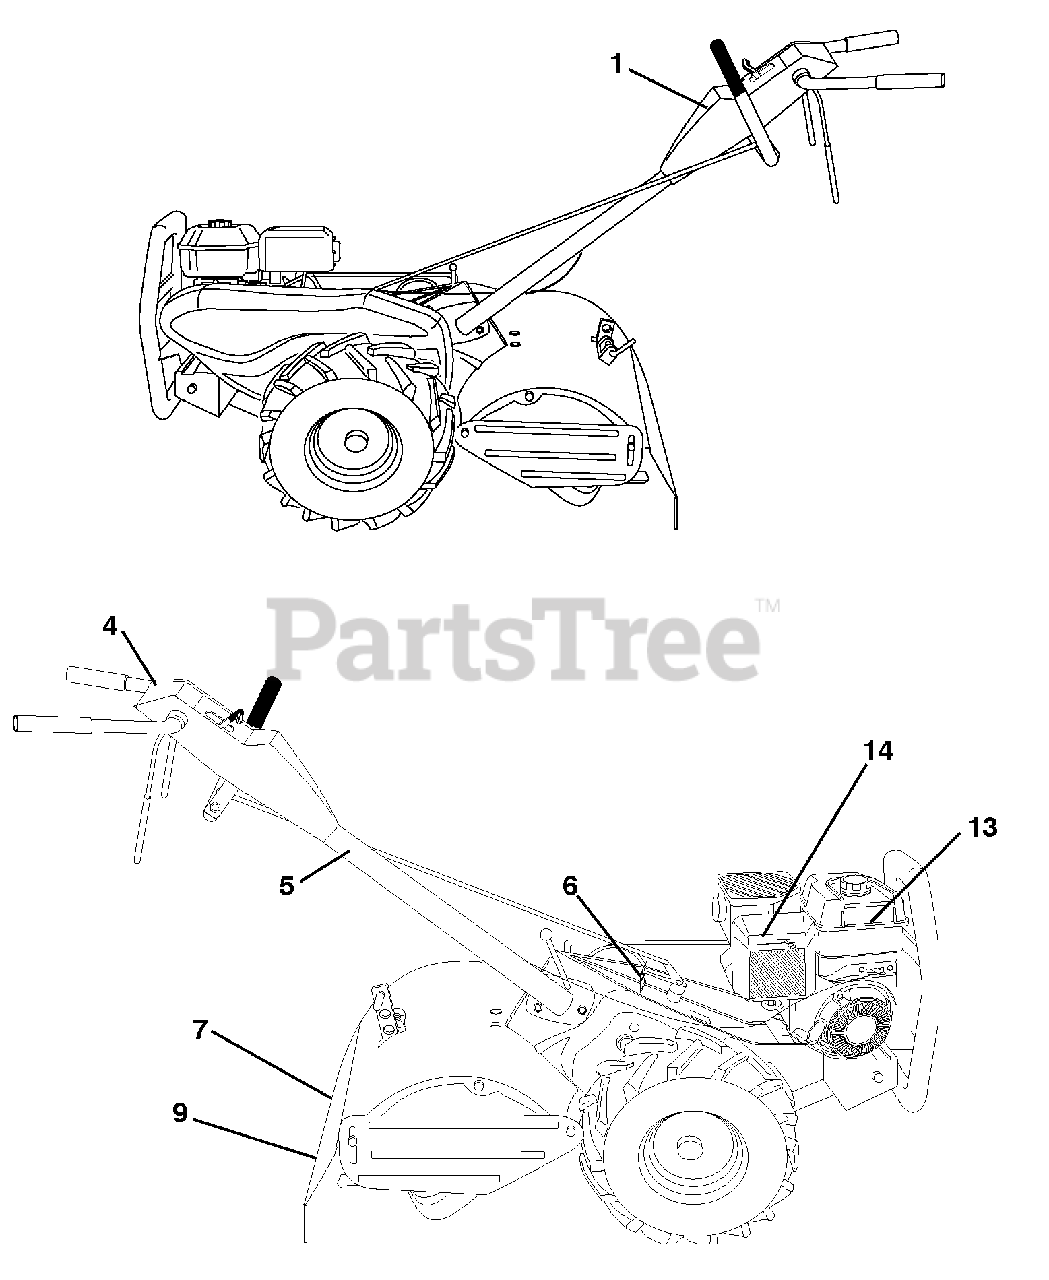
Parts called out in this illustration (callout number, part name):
1	Decal, CNTRL PNL
4	Decal, Instruction, Tilling
5	Decal, Hand Placement
6	Decal, Shift Indicator
7	Decal, Warning Shield
9	Decal, Warning, Rotating Tines
13	Decal, B&S Tank
14	Decal, B&S, Air Cleaner
14	Manual, Operator's, English/French
14	Manual, Repair Parts, English/French
